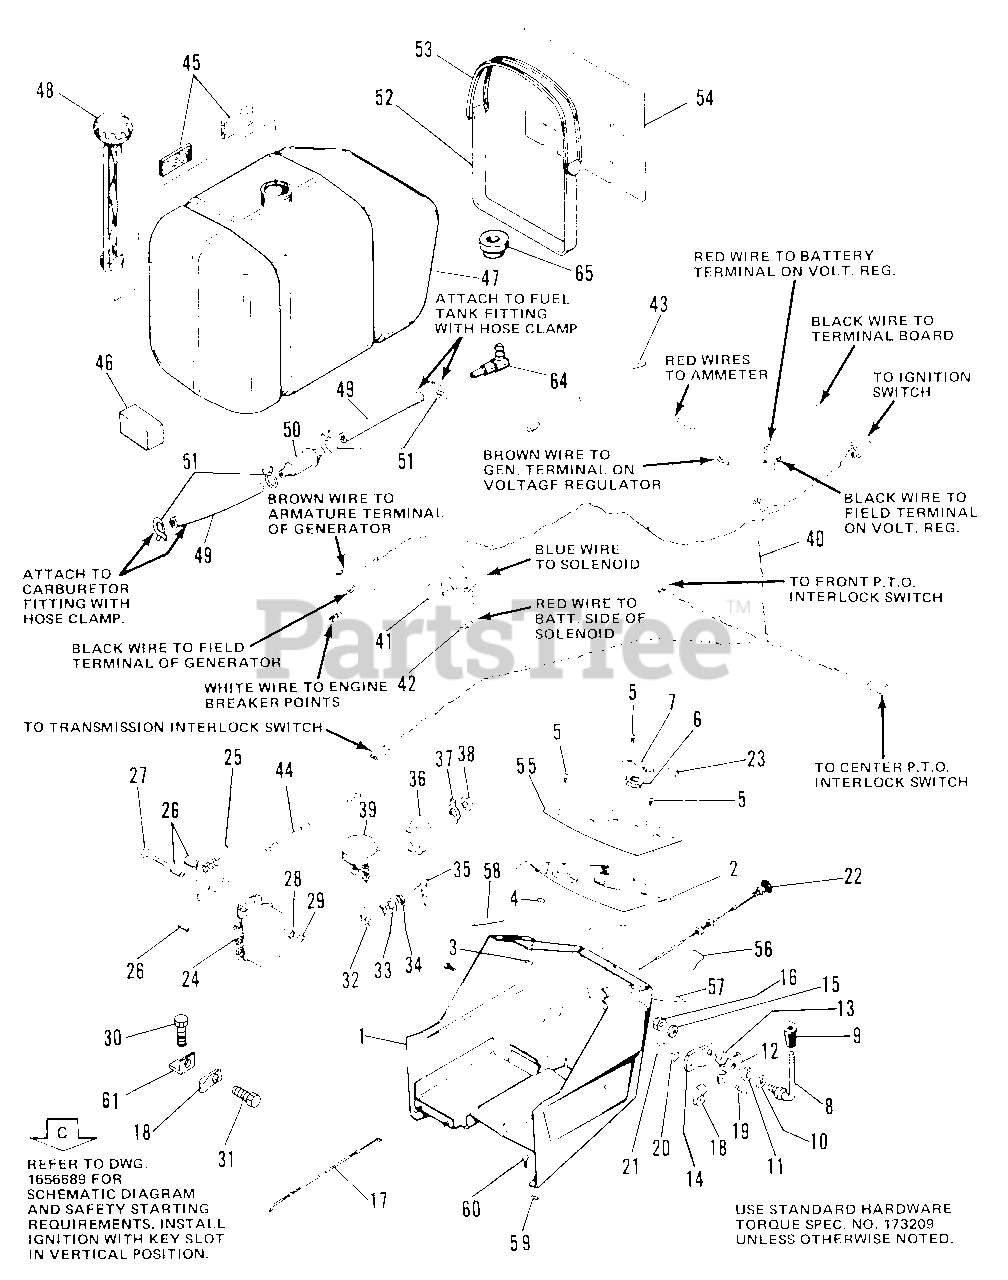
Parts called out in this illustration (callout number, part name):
1	DASH ASSEMBLY
2	PANEL, Instrument
3	NUT, Retainer, Tinn.
4	WASHER, Plain, 3/16
5	SCREW, Mach. Rd. Hd., 1/4-20 x 1/2
7	PLATE STEERING, Adj.
8	HANDLE, Clutch Control
9	KNOB, Tapered
12	STOP, Throttle
14	ARM, Throttle
15	LOCKWASHER, Dished Shakeproof, 3/8
16	LOCKNUT, Hex, 3/8-16
17	CONTROL, Throttle
18	CLIP, Bowden Wire
19	SCREW, Rd. Hd., No.10-32 x 1/2
20	LOCKWASHER, External, No.10
21	NUT, Mach. Hex, No.10-32
22	CONTROL, Choke
23	PLUG, Button
24	REGULATOR, Voltage
25	BOARD, Terminal
27	CAPSCREW, Hex Hd., 1/4-20 x 1-3/4
28	LOCKWASHER, Shakerproof, 1/4
29	NUT, Hex,1/4-20
30	SCREW, Hex Hd., 1/4-20 x 5/8
31	SCREW,Taptite, No.10-24 x 1/2
32	SWITCH, Ignition
33	LOCKWASHER, Internal, 5/8
34	NUT, Hex Special
35	KEY & RING ASSEMBLY
36	SWITCH, Toggle
37	PLATE
38	NUT
40	HARNESS ASSEMBLY
41	CIRCUIT BREAKER
42	WIRE ASSEMBLY
43	WIRE ASSEMBLY
44	WIRE ASSEMBLY, Light Switch
45	GASKET, Felt
46	PAD, Fuel Tank
48	CAP, Fuel Tank
50	FILTER, Fuel
51	CLAMP, Hose
52	STRAP, Tank
53	STRAP, Fuel Tank
54	INSULATION, Fuel Tank
55	DECAL, Instrument Panel
56	DECAL, Ignition
57	DECAL, Throttle Control
58	DECAL, 6 Speed Control
59	NUT, Speed, Tinn.
60	SCREW, Hex Hd. Thd. Forming, No.14 x 3/4
61	BRACKET, Cable
62	ELBOW, Fuel Tank
63	BUSHING, Fuel Tank
